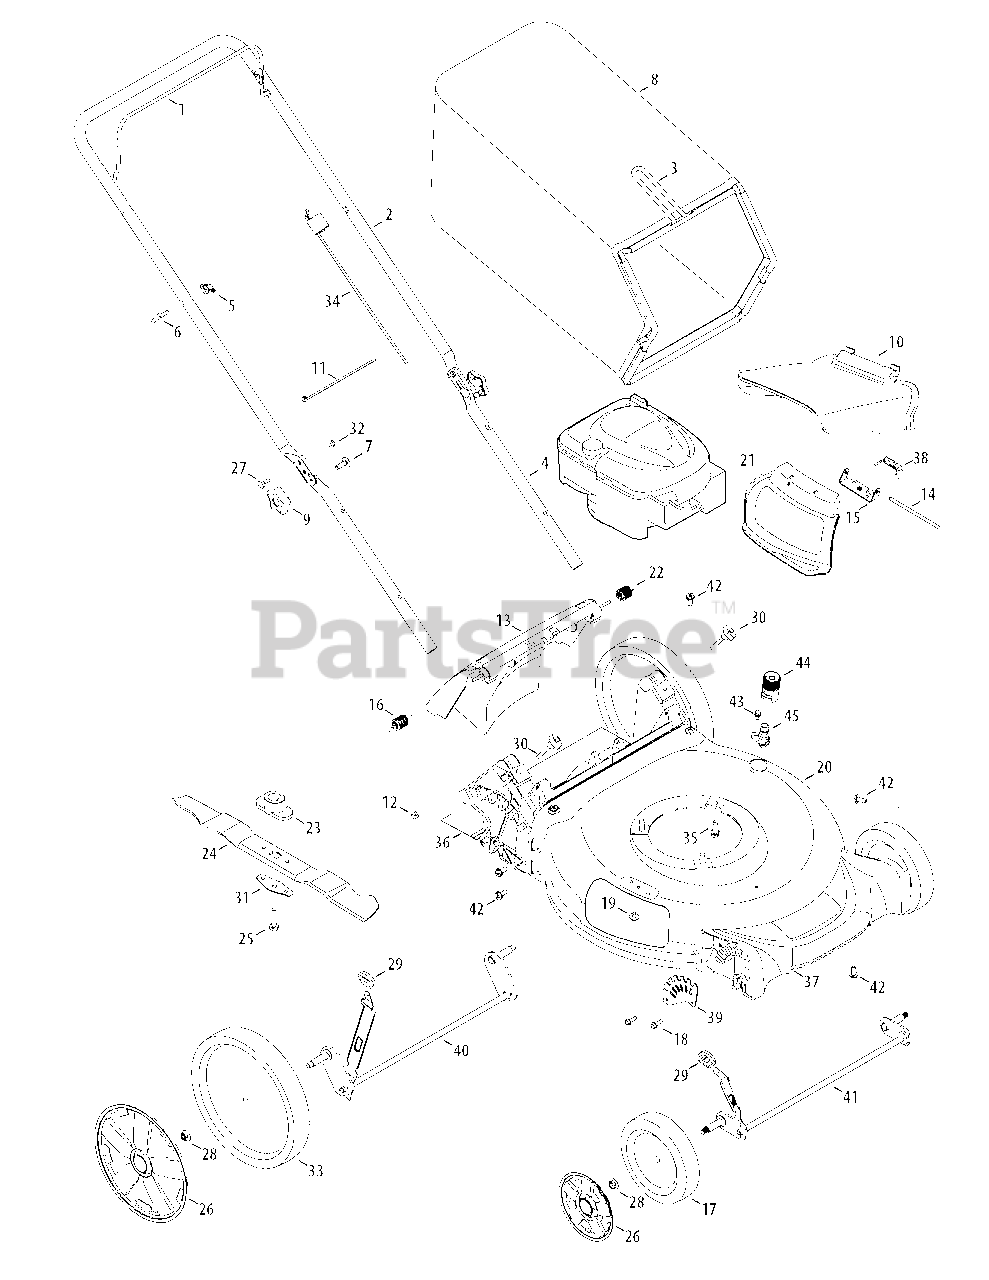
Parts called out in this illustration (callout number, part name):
1	Blade Control
2	Upper Handle
4	Lower Handle
5	Wing Nut
6	Rope Guide
7	Carriage Screw ,5/16-18
8	Grass Bag
9	Hand Knob
10	Side Chute
11	Cable Tie
12	Nut, Sq., 1/4-20
13	Rear Discharge Door Assembly
14	Hinge Pin
15	Chute Deflector Bracket
16	Torsion Spring - RH
17	Wheel, 7 x 2
18	Screw, 1/4-15 x .750
19	Screw, 1/4-20 x .500
20	Deck - 21"
21	Hinged Mulch Plug Assembly
22	Torsion Spring - LH
23	Blade Adapter
24	Mulching Blade
25	Screw , 3/8-24 x 1.50
26	Hub Cap - Front
27	Sldr. Screw, .375 x .126 x 1/4-20
28	Flange Lock Nut, 3/8-16
29	Adjustment Lever Knob
30	Wing Knob
31	Blade Bell Support
32	Nut, Flange Lock, 1/4-20
33	Wheel, 11 x 2
34	Control Cable
35	TT Screw, 3/8-16 x 1.0
36	Trail shield
37	Front Cover
38	Torsion Spring
39	Front Height Adjuster Plate
40	Rear Axle Assembly
41	Front Axle Assembly
42	Screw, 5/16-14 x .750
43	Shldr. Screw, 1/4-20 x .50
44	Water Nozzle Adapter
45	Deck Wash Nozzle
